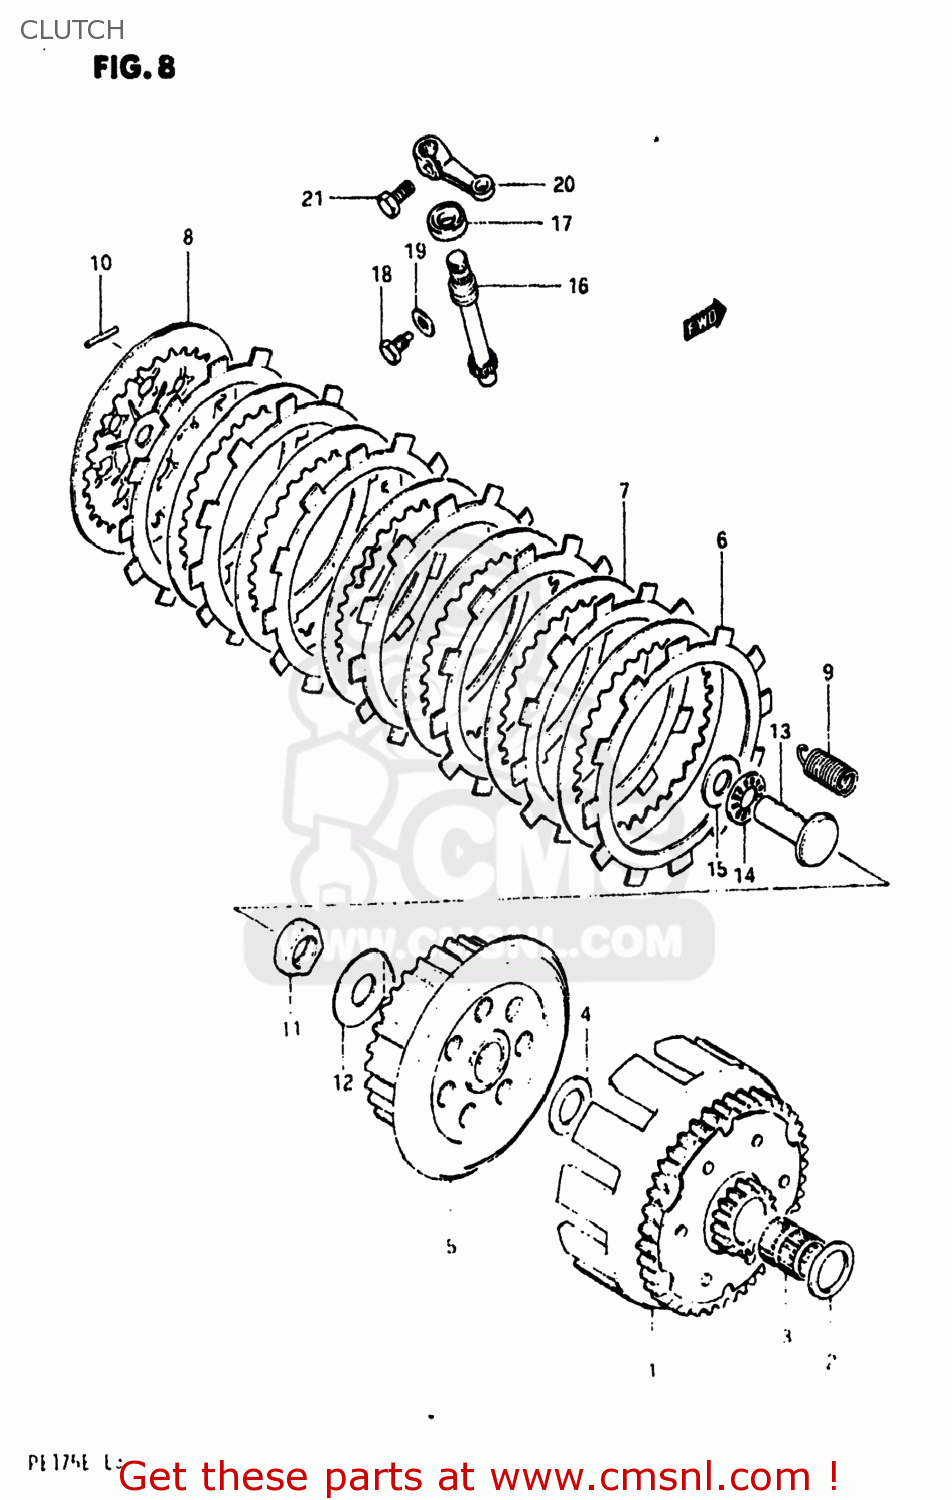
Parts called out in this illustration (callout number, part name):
1	GEAR ASSEMBLY,PRIMARY DRIVE
2	WASHER
3	BEARING(20X25X26)
4	WASHER
5	HUB,CLUTCH SLEEVE
6	PLATE,CLUTCH DRIVE
7	PLATE,CLUTCH DRIVEN
8	PLATE,CLUTCH PRESSURE
9	SPRING
10	PIN(2.5X19.8)
11	NUT
12	WASHER,LOCK
13	RACK,CLUTCH RELEASE
14	BEARING(10X22X2.8)
15	WASHER(10.1X21.4X0.8)
16	PINION,CLUTCH RELEASE
17	SEAL,OIL (10X17X5)
18	BOLT(6X12)
19	WASHER
20	ARM,CLUTCH RELEASE
21	BOLT, UPPER
